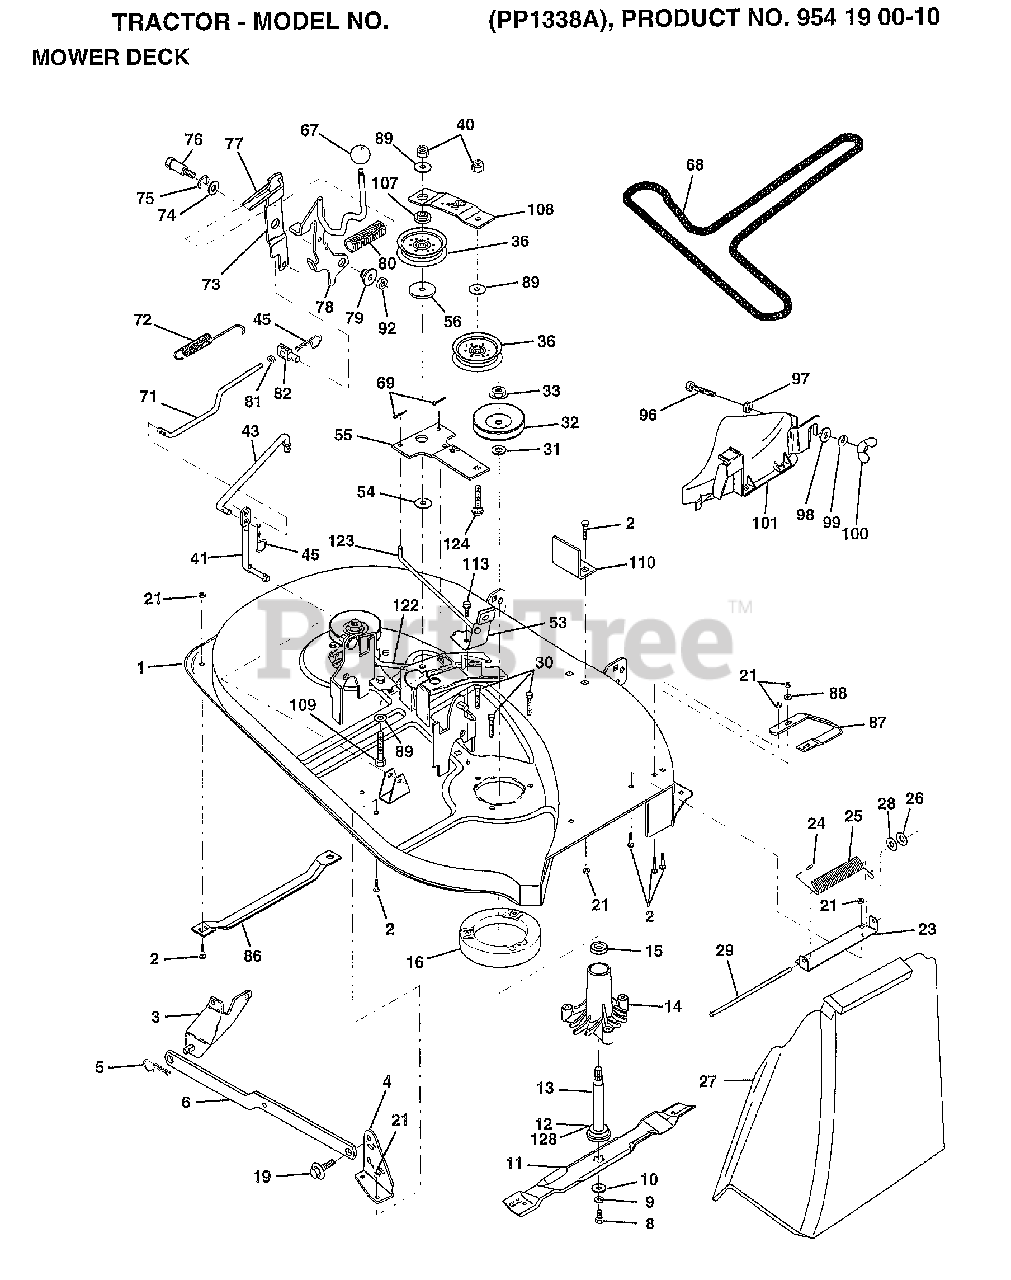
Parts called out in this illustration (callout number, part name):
1	"HOUSING ASSY.42"""
3	BRKT ASM SWAY BAR
4	BRKT DECK SW BAR
8	BLADE BOLT
10	WASHER.HARD.BLADE
11	"BLADE.38""V.MULCH"
12	BEARING.BALL
14	HSG ASM MANDREL
15	BEARING
16	STRIPPER RND MWR
19	BOLT SHD 5/16-18
20	BAFFLE VORTEX 42
23	BRKT DEFLECTOR
24	CAP-SLEEVE LT
25	SPRING TORSION
26	NUT PUSH M
27	DEFLECTOR-SHLD T
28	WASHER
29	ROD-HINGE T
31	WASHER
32	PULLEY.MANDREL.38
36	FLAT IDLER PULLEY
37	WASHER
41	PIVOT ROD
43	CLUTCH ROD SECOND
45	RETAINER M
53	BRAKE ASM
54	HARDENED WASHER
55	IDLER ARM ASSY
56	SPACER RETAINER
67	KNOB T(3/8 HOLE)
68	BELT.V.T-PATH
71	ROD CLUTCH 38/42
72	RETURN SPRING
73	CLUTCH ARM SECOND
74	WASHER
75	RING
76	SHOULDER BOLT
77	SPRING KEEPER
78	LEVER ASM-CLUTCH
79	BUSHING
80	SPRING.CLUTCH.MWR
81	NUT
82	TRUNION ADJ
86	RUNNER-LH M
87	RUNNER RH
88	WASHER M
89	WASHER GT
92	NUT
96	HEX BOLT
97	LOCKNUT
99	LOCKWASHER
100	WINGNUT
101	COVER.MULCHER
107	RETAINER SPACER
108	IDLER ARM STIFF
109	BOLT
110	UPSTOP DECK FT 38
113	SCREW
122	BRAKE ROD LH
123	BRAKE ROD RH
124	BOLT
128	WASHER.FELT.
